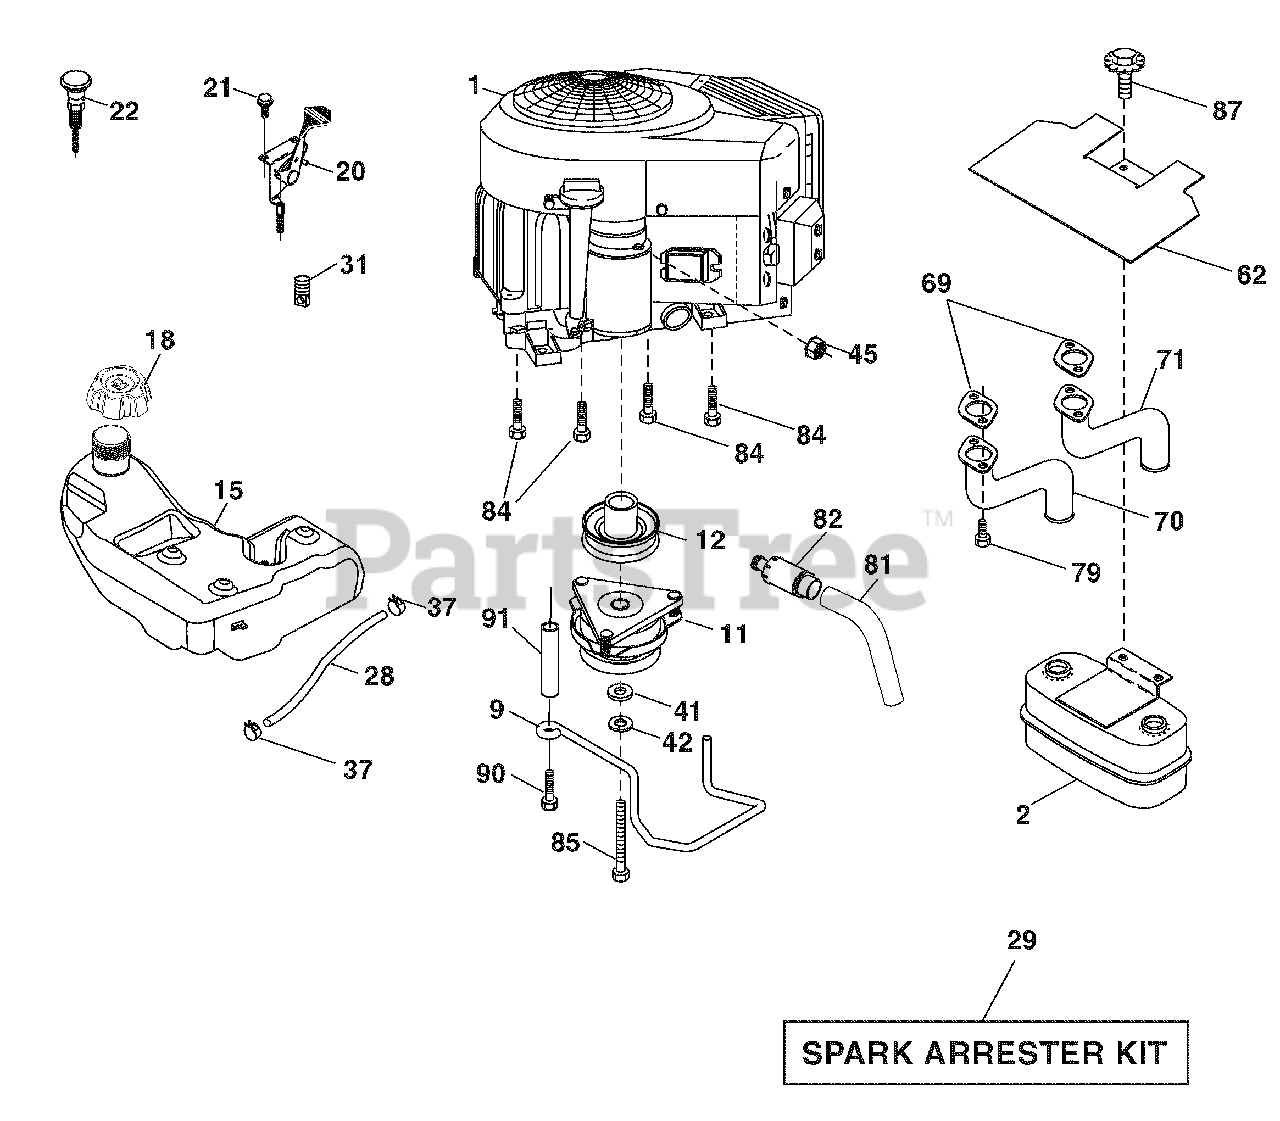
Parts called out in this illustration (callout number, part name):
9	Keeper Belt Engine
11	Clutch
12	Pulley Engine
15	Tank Fuel
18	Cap Asm
20	Control Throttle
21	Screw #10 x .750 BOS Thread
22	Choke Control
28	Fuel Line
29	Spark Arrester Kit
31	Clip Push-in Hinged
37	Clamp Hose
41	Washer 1-1/2 OD x 15/32 ID x .250
42	Washer Lock 7/16
45	Nut Keps Hex 1/4-20 unc
62	Heat Shield
70	Tube Exhaust LH
71	Exhaust Tube RH
79	Screw Socket HD 5/16-18 x 1
81	Tube Drain Oil Easy
82	Plug Drain Oil
84	Screw 3/8-16 x 1-1/4
85	Bolt Hex 7/16-20 x 4 x Gr. 5-1.5 Thr
87	Bolt 5/16-18 UNC x 3/4 w/Sems
90	Screw 3/8-16 x 1
